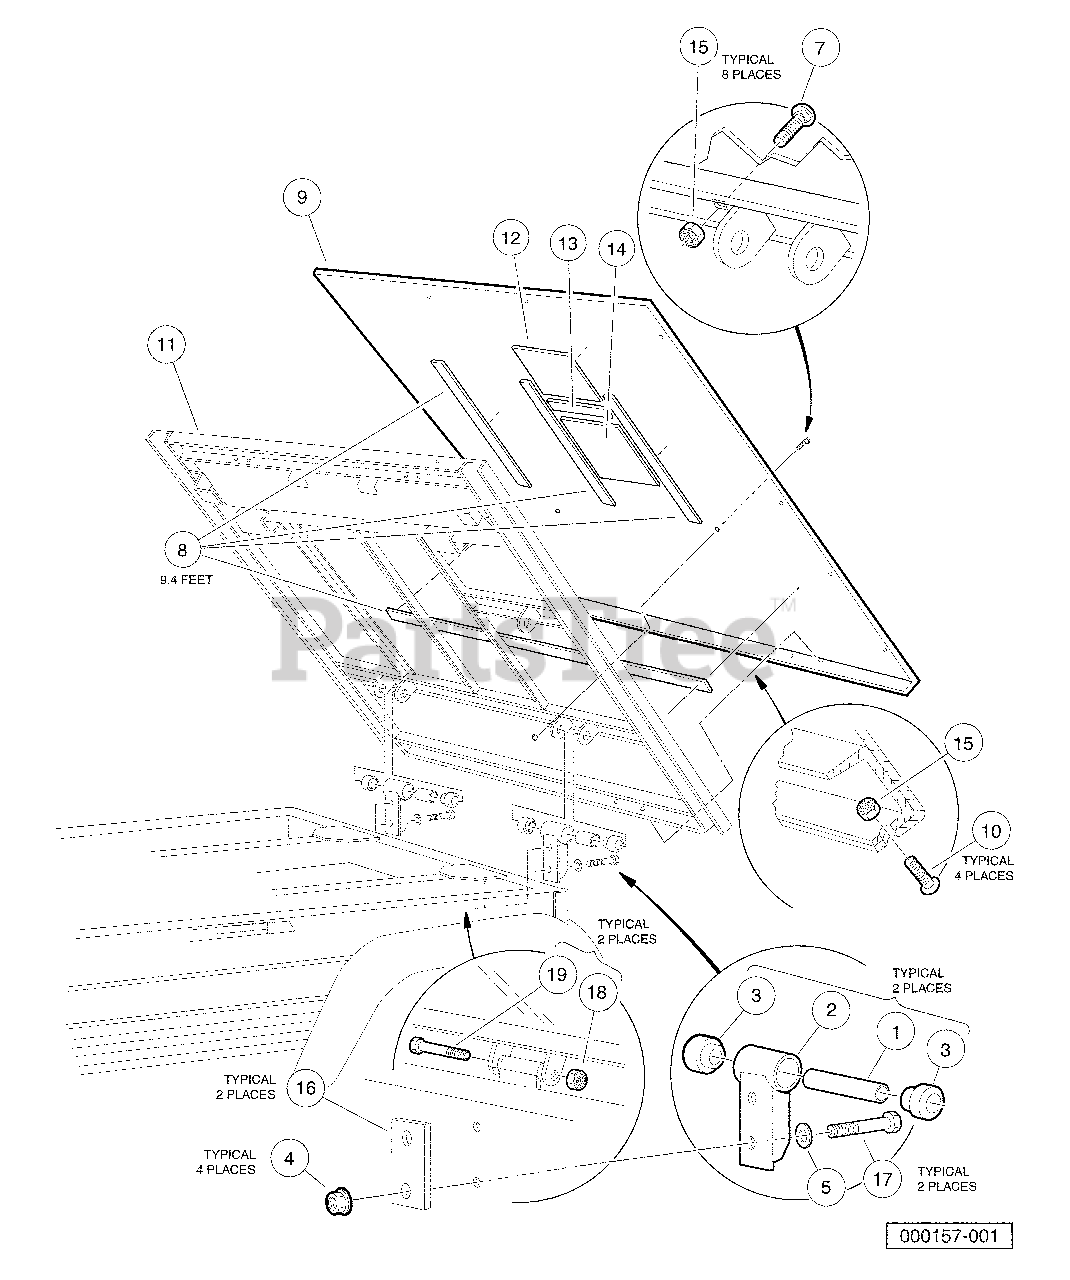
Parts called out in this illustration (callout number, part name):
1	Bushing, Steel
3	Bushing, Urethane
4	Locknut, 3/8-16 Flanged Dimple
5	Washer, 3/8 Type B Hard Flat
6	Assembly, Tilt Bed, Electric Lift
7	Bolt, Carriage, 5/16-18 X 1.00
8	Tape, Vinyl Foam 1/8" x 3/4"
9	Plate, Floor Bed
10	Frame Assembly
11	Screw, 5/16-18 X 0.88 Torx Truss-Head
12	Foam, Barrier, Heat, Bed, Frt
13	Foam, Barrier, Heat, Bed, Rail
14	Locknut, 5/16-18 Nylon Insert
15	Plate, Back
16	Bolt, 3/8-16 X 3.00 Hex Head
17	Locknut, 3/8-16 Hex
18	Screw, 3/8-16 X 3.375 Hex Cap
